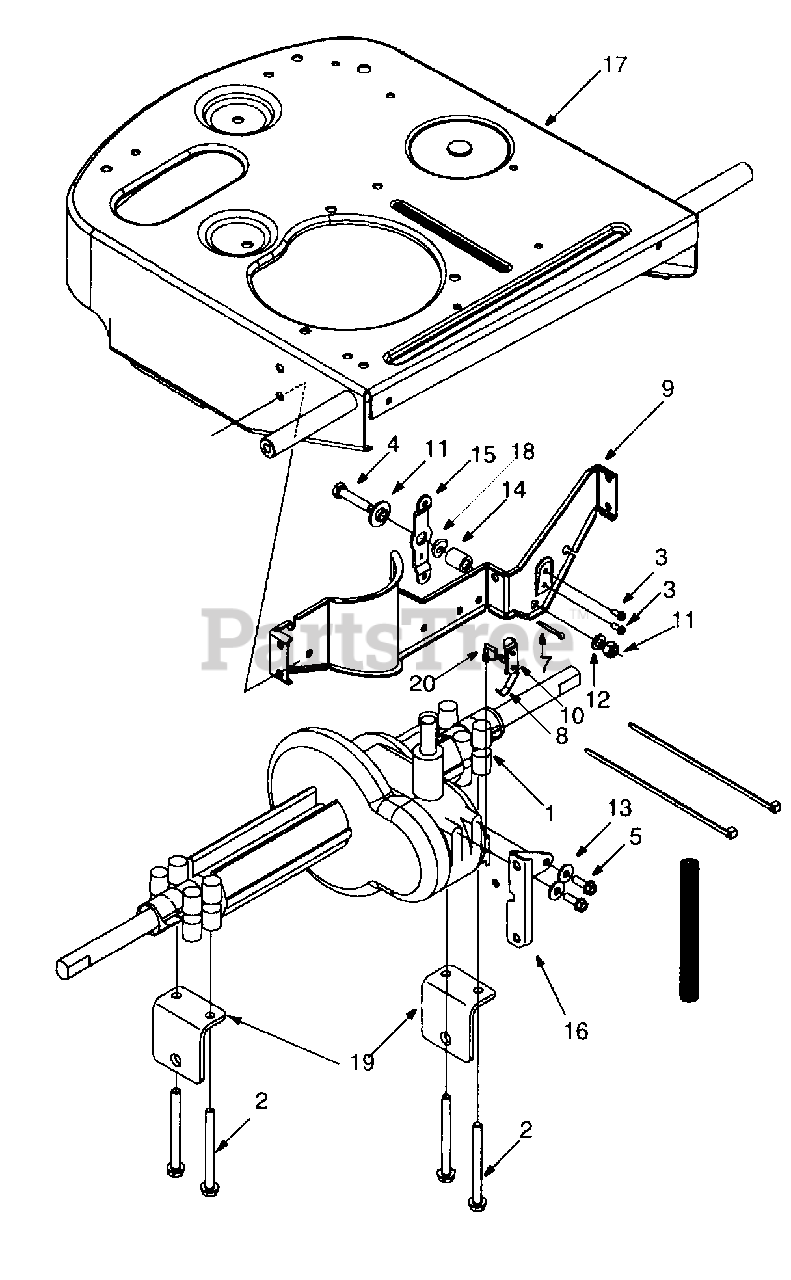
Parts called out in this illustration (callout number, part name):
1	Harness Assembly Adapter
2	Hex TT Screw 5/16-18 x 3.50
3	Hex Washer Head Self-Tap. Screw
4	Hex Screw 5/16-18 x 1.5 Gr. 5
5	Thd. Forming Scr. 1/4-20 x .75
7	Cotter Pin
8	Insulator Nut Plate
11	Shoulder Bushing
12	Lock Washer 5/16
13	Flat Washer .28 I.D. x .74 O.D. x .083
14	Spacer
15	Shift Lever
16	Transaxle Bracket
